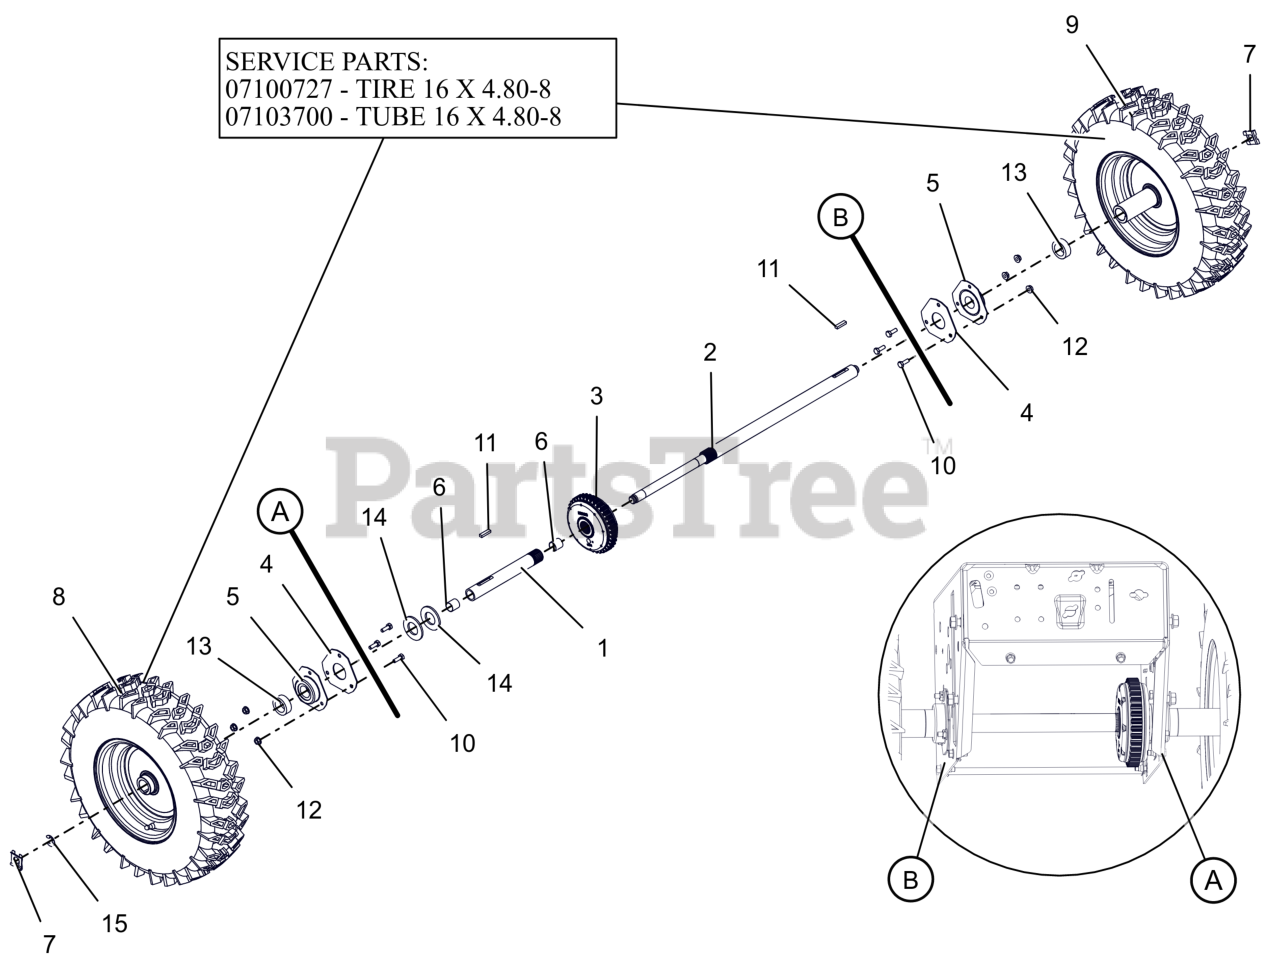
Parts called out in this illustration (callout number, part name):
1	AXLE, SHORT-AUTO W/BUSHINGS
2	AXLE, LONG-PRO AUTO DIFF
3	DIFFERENTIAL, AUTOMATIC
4	PLATE, BEARING SPACER
5	BRG-FLG 1.003/1.000 3 BOLT
6	BSHG-SLV .706X.764X.75 BRZ
7	CLIP, SNAP .625 DIA
8	TIRE/WHEEL,RH 16X4.8-8 DIFF T2
8	TIRE, 4.80-8 K478
8	TUBE
9	TIRE/WHEEL,LH 16X4.8-8 DIFF T2
9	TIRE, 4.80-8 K478
9	TUBE
10	BLT, HEX .25-20X.75 G5 ZCC
11	KEY-RECT .25X.188X1.00
12	NUT-LK-CTR-FLG .25-20 ZC120
13	SPACER, PRO AXLE BEARING
14	WSHR, FLT 1.062X2.000X.134 ZCC
15	RG-RTNG-EXT .625X.042
